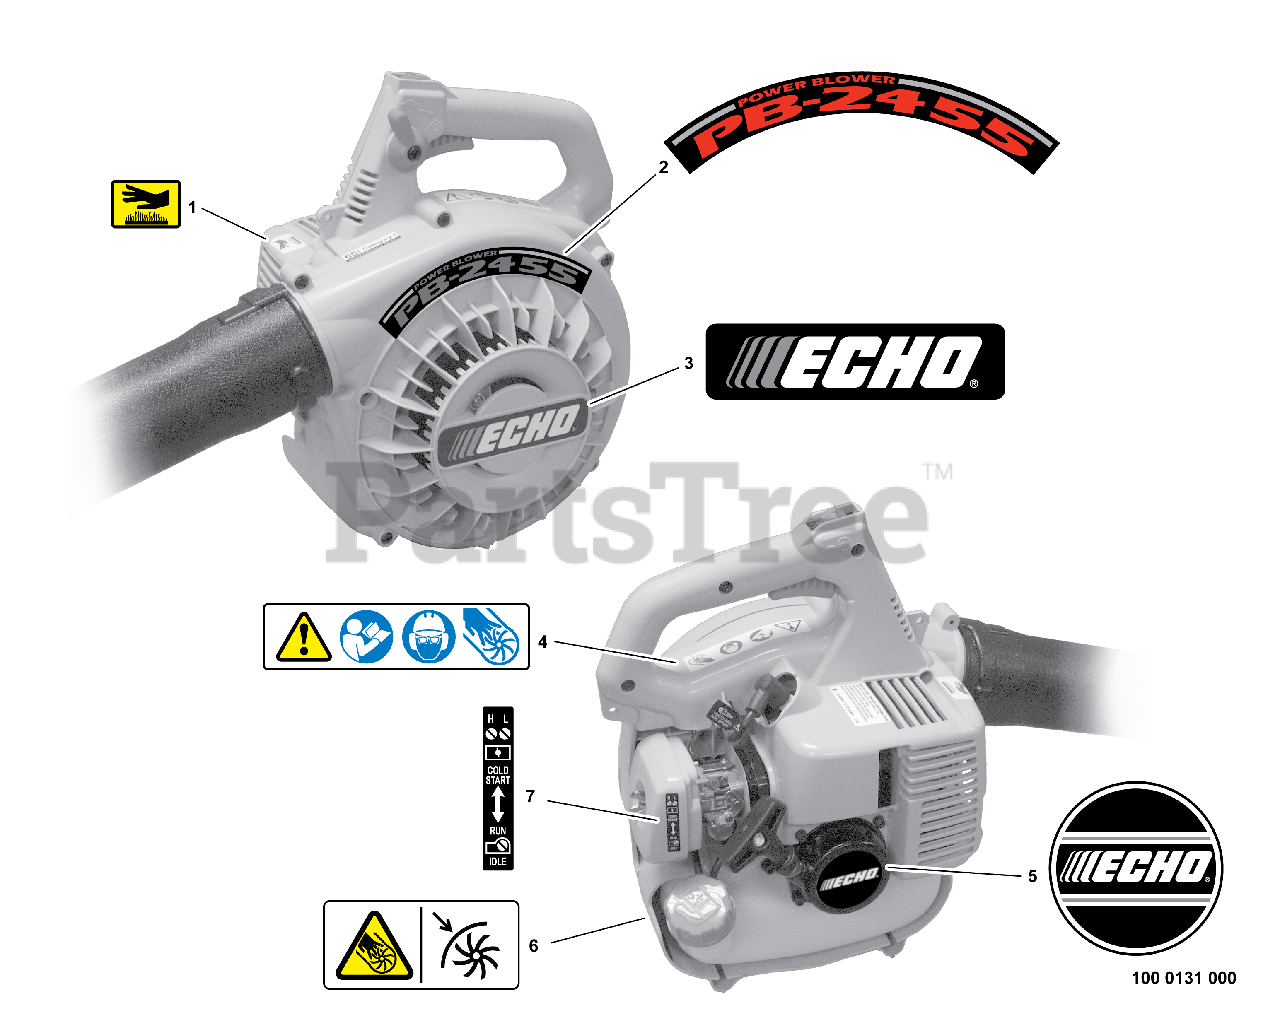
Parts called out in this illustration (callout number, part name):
1	LABEL - HOT SURFACE
2	LABEL - NOISE 65dB(A) CAT I
3	LABEL - MODEL PB-2155
4	LABEL - ECHO
5	LABEL - NOISE 65dB(A) CAT I
6	LABEL - ECHO
7	LABEL - CAUTION
8	LABEL - CHOKE
